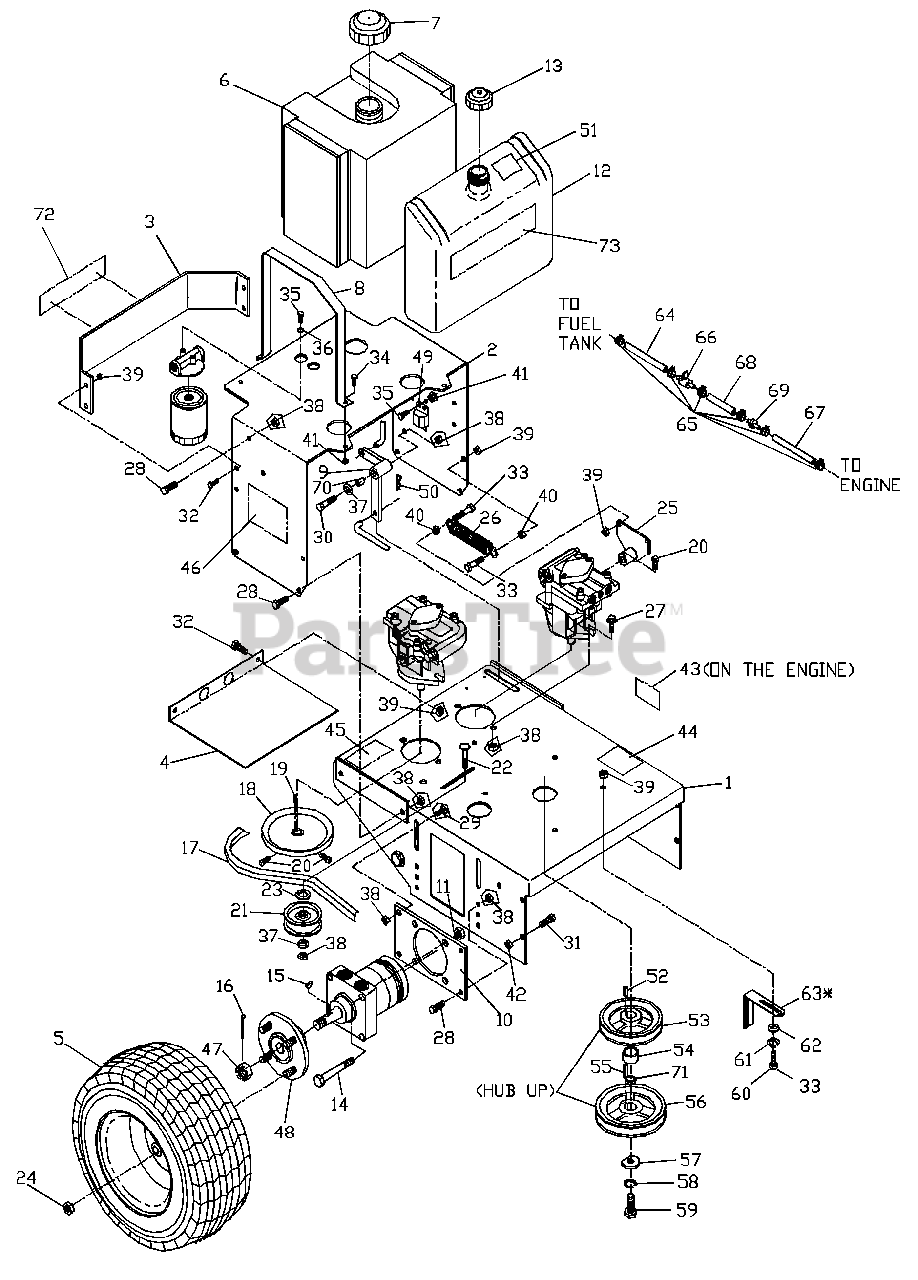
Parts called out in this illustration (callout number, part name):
1	REAR DECK W/DECALS
2	TANK SUPPORT, WLDMT.
4	LOWER BELTSHIELD
5	WHEEL, COMPLETE
5	RIM
5	VALVE STEM
8	TANK STRAP
9	BELL CRANK
10	MOTOR MOUNT, 36
10	MOTOR MOUNT, 48
11	NYLOC NUT 1/2C
14	HCS 1/2C X 2 3/4
15	KEY #808 WOODRUFF
19	KEY METRIC
20	5/16C X 5/8 SQ. HEAD
21	IDLER PULLEY
22	RHSNB 3/8C X 2
23	1/2 FLAT WASHER
24	1/2F LUGNUT
25	PUMP ARM WLDMT.
27	HFCS 3/8C X 1
28	HCS 3/8C X 1
29	RHSNB 3/8C X 1
30	HCS 3/8C X 2
31	HCS 7/16C X 1
32	HCS 5/16C X 3/4
33	HCS 5/16C X 1 3/4
34	HCS 1/4C X 1
35	HCS 1/4C X 5/8
36	1/4 LOCKWASHER
37	3/8 FLAT WASHER
38	NUT 3/8C CENTERLOCK
39	NUT 5/16C CENTERLOCK
39	(17 Kawasaki only)
40	NUT 5/16C WHIZ
41	NUT 1/4C CENTERLOCK
42	NUT 7/16C CENTERLOCK
43	DECAL, DANGER
44	DECAL, PROP. 65
45	DECAL, DANGER
46	DECAL, SMALL CROWN
47	HEX SLOTTED NUT
50	#2 HAIRPIN
51	DECAL, HYD. FLUID
52	KEY 1/4SQ. X 3/4
55	KEY 1/4SQ. X 1 1/8
57	CRANKSHAFT WASHER
58	SLW 7/16 STD
59	HCS M10-1.5X35MM
59	HCS 7/16F X 1.5
60	HCS M8-1.25X35MM
60	HCS M8-1.25 X 30MM GR8
61	SLW 5/16 STD.
62	WASHER 5/16 STD.
63	BELT GUIDE
63	(36" MODEL)
64	16" GAS LINE
65	HOSE CLAMP
66	FUEL VALVE
67	10" GAS LINE
68	3 1/2" GAS LINE
68	14" GAS LINE
69	FUEL FILTER
70	SLEEVE BUSHING
71	MACHINE BUSHING
72	DECAL, HUSQVARNA
73	DECAL, WH 3614
73	DECAL, WH 4817
73	DECAL, WH3615
